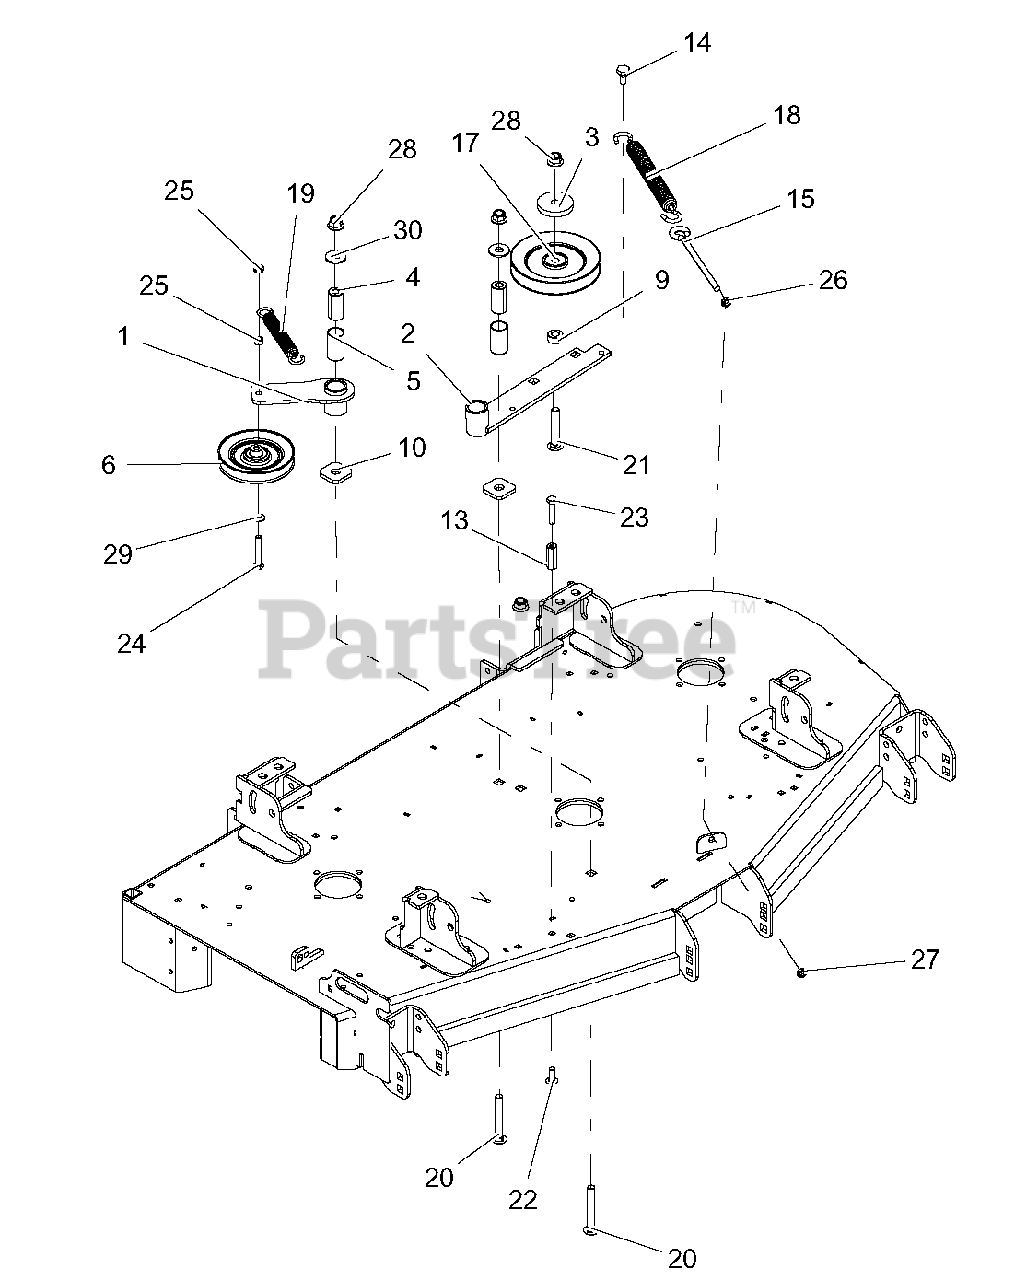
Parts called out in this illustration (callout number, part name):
1	WMT, IDLER PIVOT ARM-BLACK
2	WMT, IDLER PIVOT ARM-BLACK
3	CAP, IDLER BEARING SEALING
4	BSHG, SPCR .502X.997X2.03
5	BSHG, 1.00X1.125X1.937
6	IDLER, V-5.00" W/.69 STANDOFF
9	BSHG, SPCR .502 X .997.50 PM
10	WSHR, -FLT.640X1.75X.250
13	NUT-HEX COUPLING
14	BLT, SHLDR EP .38-16X.30 HEX YZ
15	BOLT, .38-16X6.00 .62 DIA EYE
17	SHEAVE, .50" ID X 6.00" OD V-IDLER
18	SPRG, EXTENSION
19	SPRG, EXTENSION
20	BLT-RDHDSQNK .50-13X3.50 G5 Y
21	BLT-RDHDSQNK .50-13X3.00 G5 Y
22	BLT-RDHDSHSQNK.38-16X1.0 G5YZ
23	BLT-HEX .38-16X1.75 GR5 YWZC
24	BLT-HEX .38-16X2.25 GR5 YWZC
25	NUT-LK-CTR .38-16 YWZC
26	NUT, JAM .375-16 YWZC
27	@NUT-LK-CTR-JAM .375-16 YWZC
28	NUT-LK-NYL-FLG .50-13 YWZC
29	WSHR-FL-STL.406X.812X.065 YWZ
30	WSHR-FL-STL.563X1.38X.109YWZC
